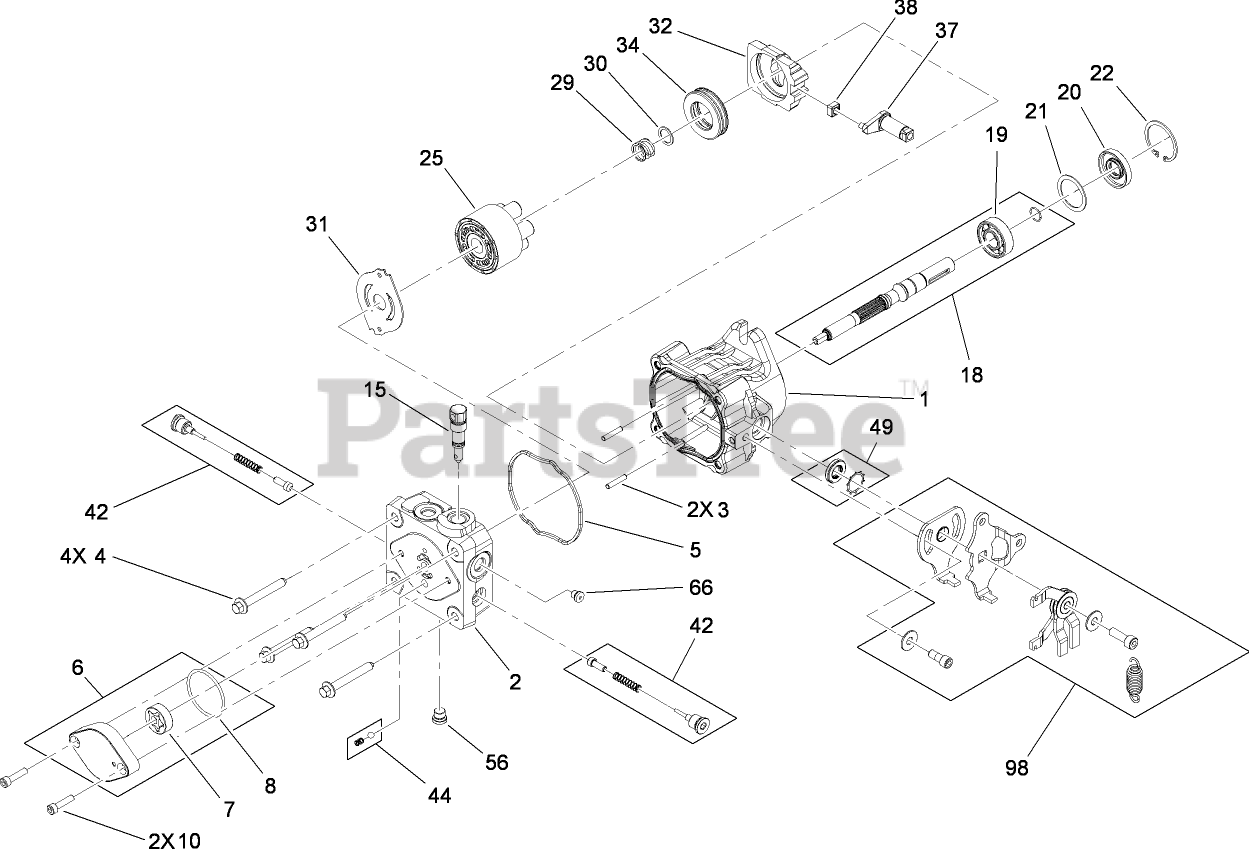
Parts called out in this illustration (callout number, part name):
1	HOUSING KIT
2	END CAP KIT (W/POPPETS)
3	PIN-HEADLESS, STRAIGHT
4	BOLT-HF
5	O-RING
6	CHARGE PUMP KIT
7	GEROTOR ASM
8	O-RING
10	CAPSCREW
15	BYPASS VALVE KIT
18	INPUT SHAFT KIT
19	BEARING-BALL
20	SEAL-LIP
21	SPACER
22	RING-RETAINING
25	CYLINDER BLOCK KIT
29	SPRING-BLOCK
30	WASHER-THRUST
31	Plate-Valve
32	SWASHPLATE-VARIABLE
34	BEARING-THRUST
37	ARM-TRUNNION, TAPERED SQUARE
38	GUIDE-SLOT
42	VALVE-CHECK (W/POPPET)
44	CHARGE RELIEF VALVE KIT
49	TRUNNION SEAL KIT
56	PLUG-HSH
66	PLUG-HSH
98	KIT-RETURN
